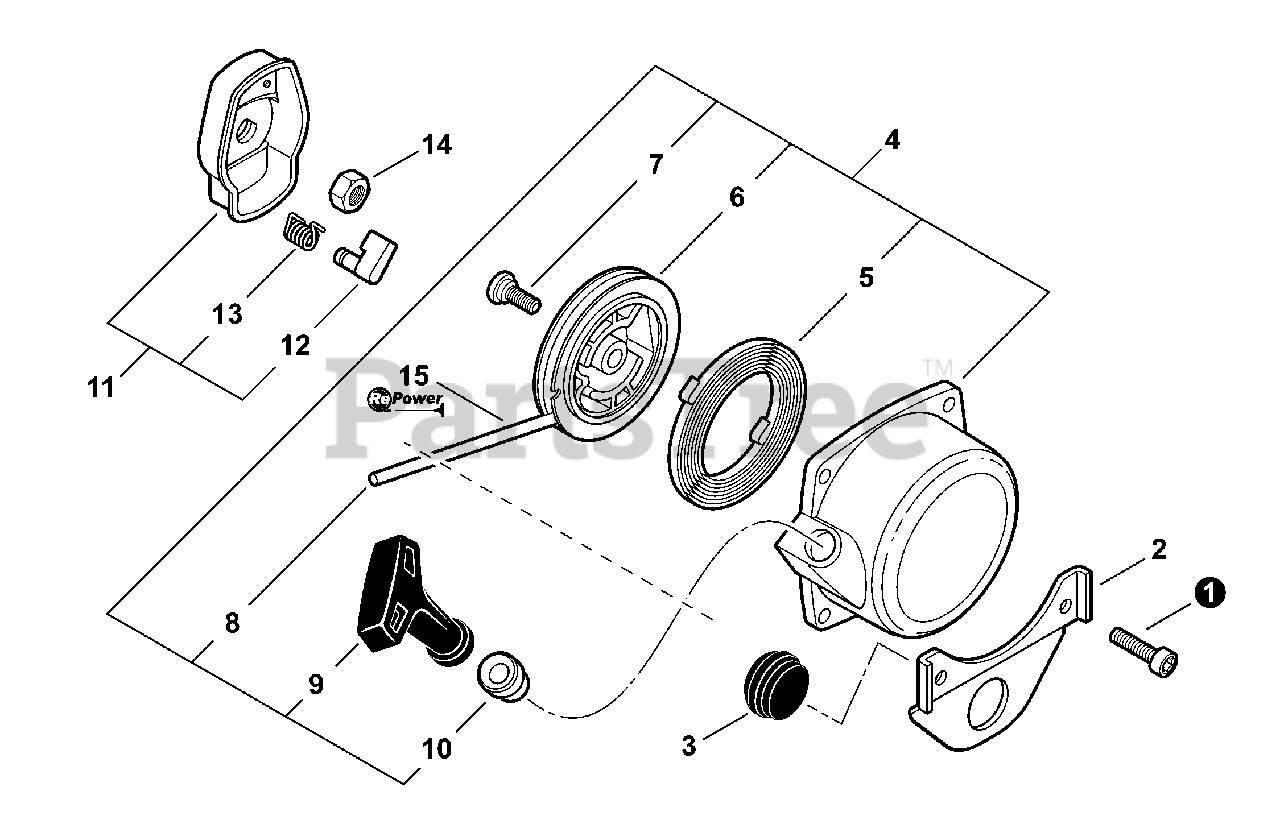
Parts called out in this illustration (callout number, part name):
1	BOLT, TORX 4×16
2	BRACKET, FUEL TANK
3	CUSHION
4	STARTER ASSY, RECOIL
5	SPRING, RECOIL
6	REEL, ROPE
7	SCREW
8	ROPE, STARTER 3.0×1000
9	GRIP, STARTER
10	GUIDE, ROPE
11	PULLEY ASSY, STARTER
12	PAWL, STARTER - BLACK
13	SPRING, RETURN
15	BULK STARTER ROPE - Ø 3.0 MM×61 M
